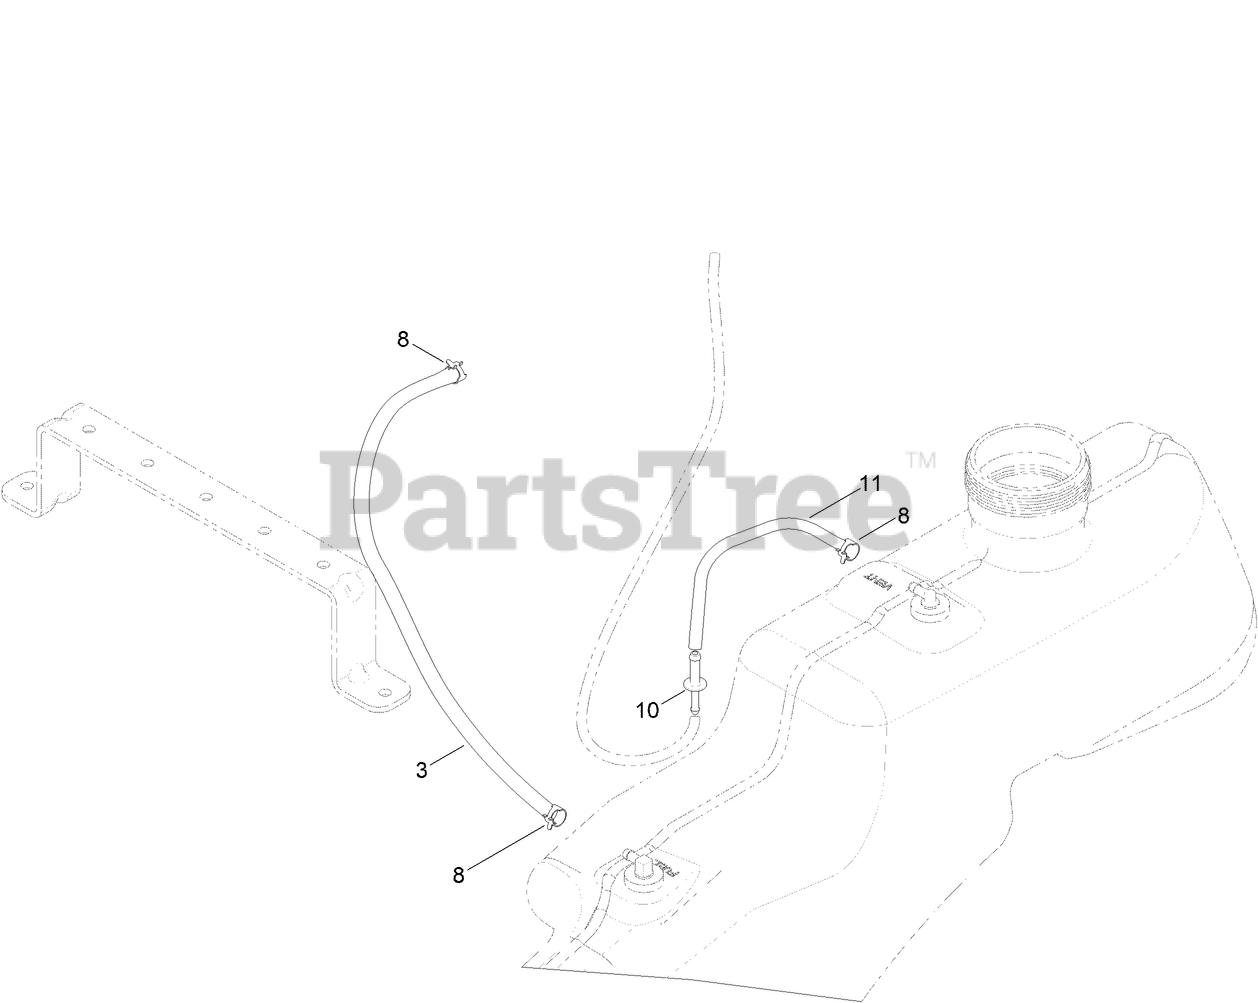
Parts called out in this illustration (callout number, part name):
3	HOSE-FUEL
8	CLAMP-HOSE
10	ADAPTOR-ORIFICE
11	HOSE-FUEL
